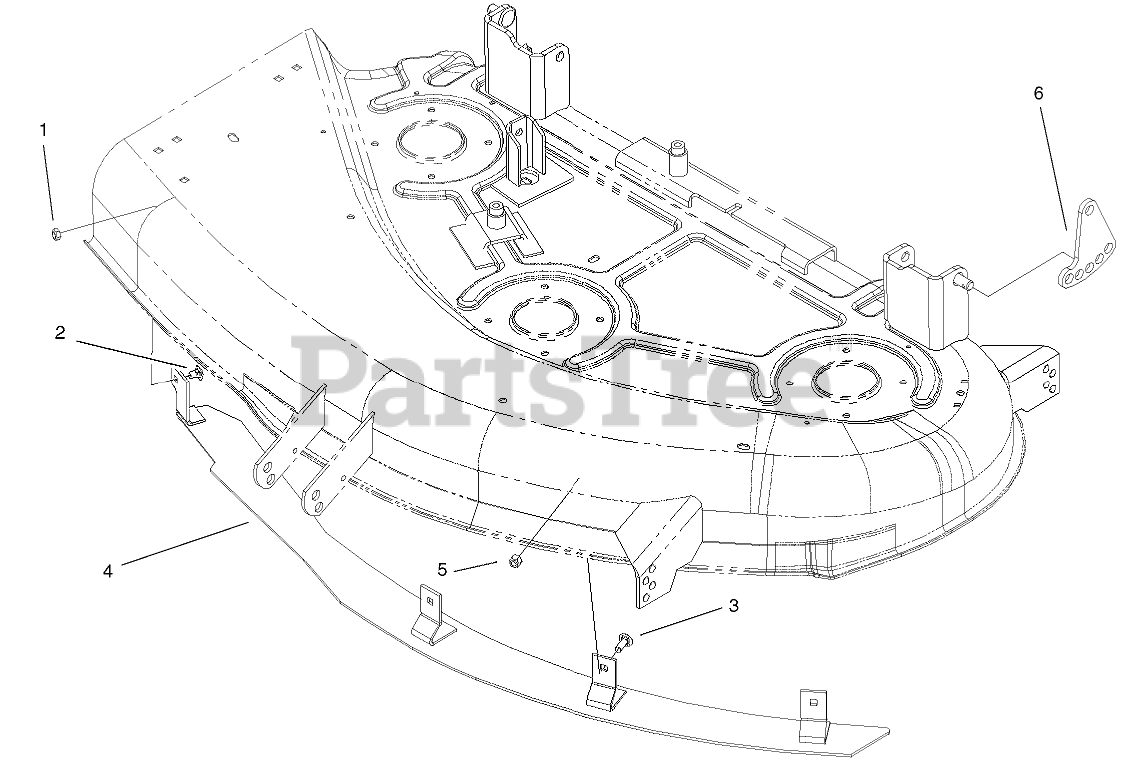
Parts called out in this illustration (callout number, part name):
1	NUT-LOCK, NI
2	SCREW-CARR
3	SCREW-CARR
5	NUT-LOCK, NI
6	LINK-HOC, ADJUSTING
